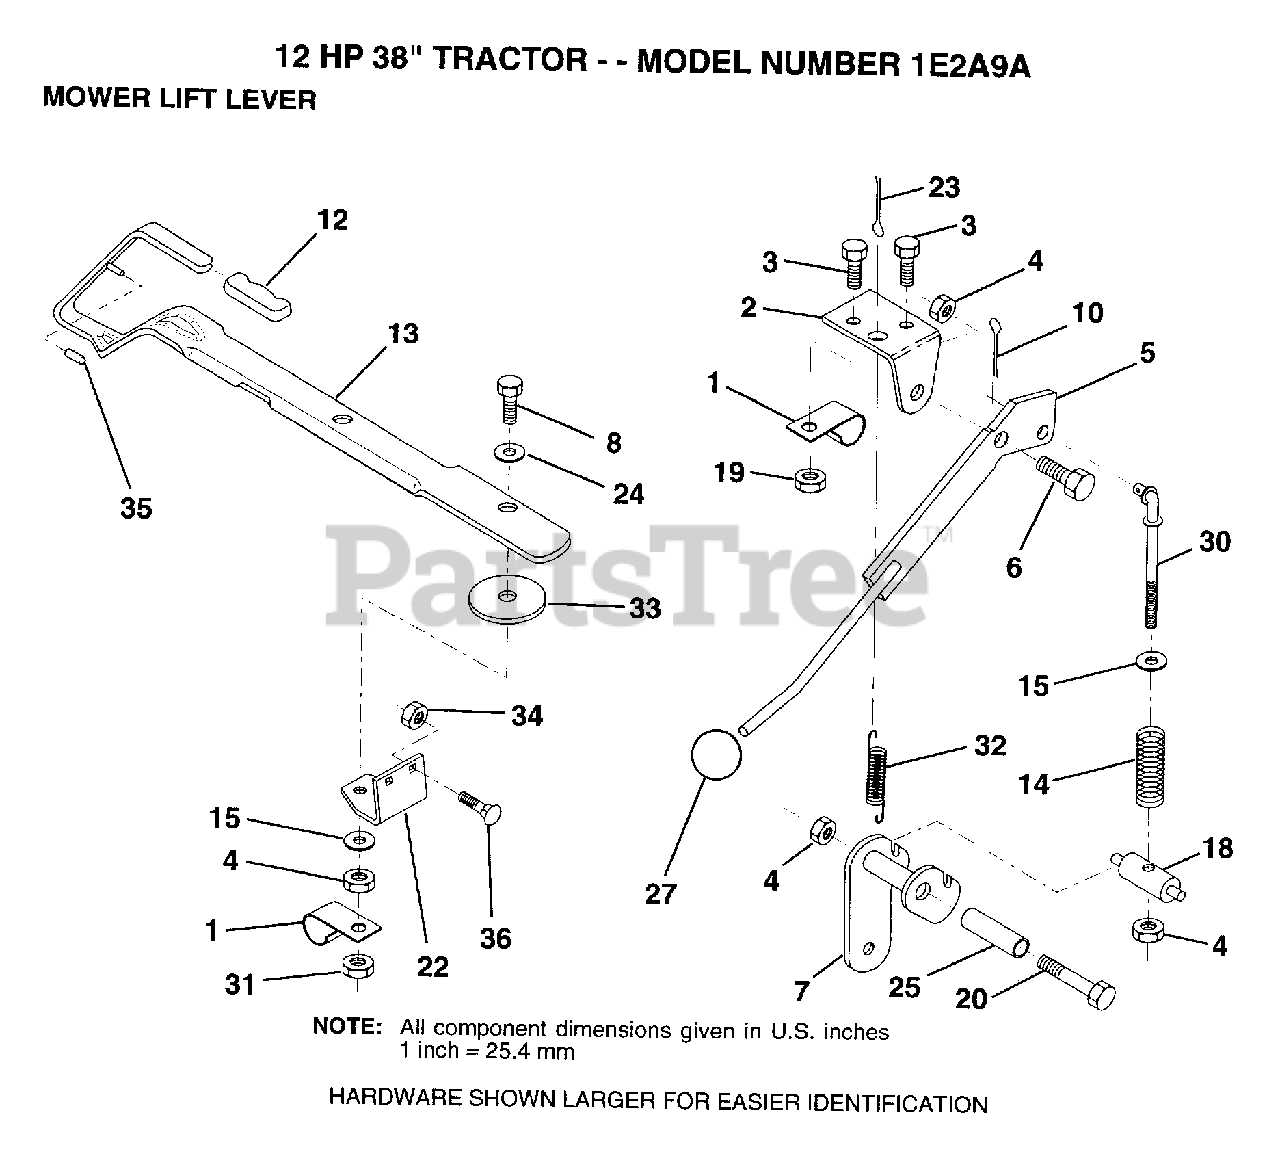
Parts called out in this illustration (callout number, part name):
1	"CLIP,INSULATOR"
2	BRKT CLUTCH
3	BOLT
5	CLUTCH LEVER AS
6	"BOLT, SHOULDER LT"
7	MWR CLUT ARM ASM
8	BOLT
10	COTTER PIN
12	GRIP HANDLE
13	LEVER LIFT LR
14	COMP CLUTCH SPRNG
15	WASHER HYT
18	TRUNNION
20	BOLT
22	LIFT LEVER BRKT
24	WASHER
25	TUBE SPACER
27	KNOB
30	ROD TENSION CLUTC
31	LOCKNUT
32	SPRING EXT
33	WASHER
35	VINYL CAP RED
36	BOLT
